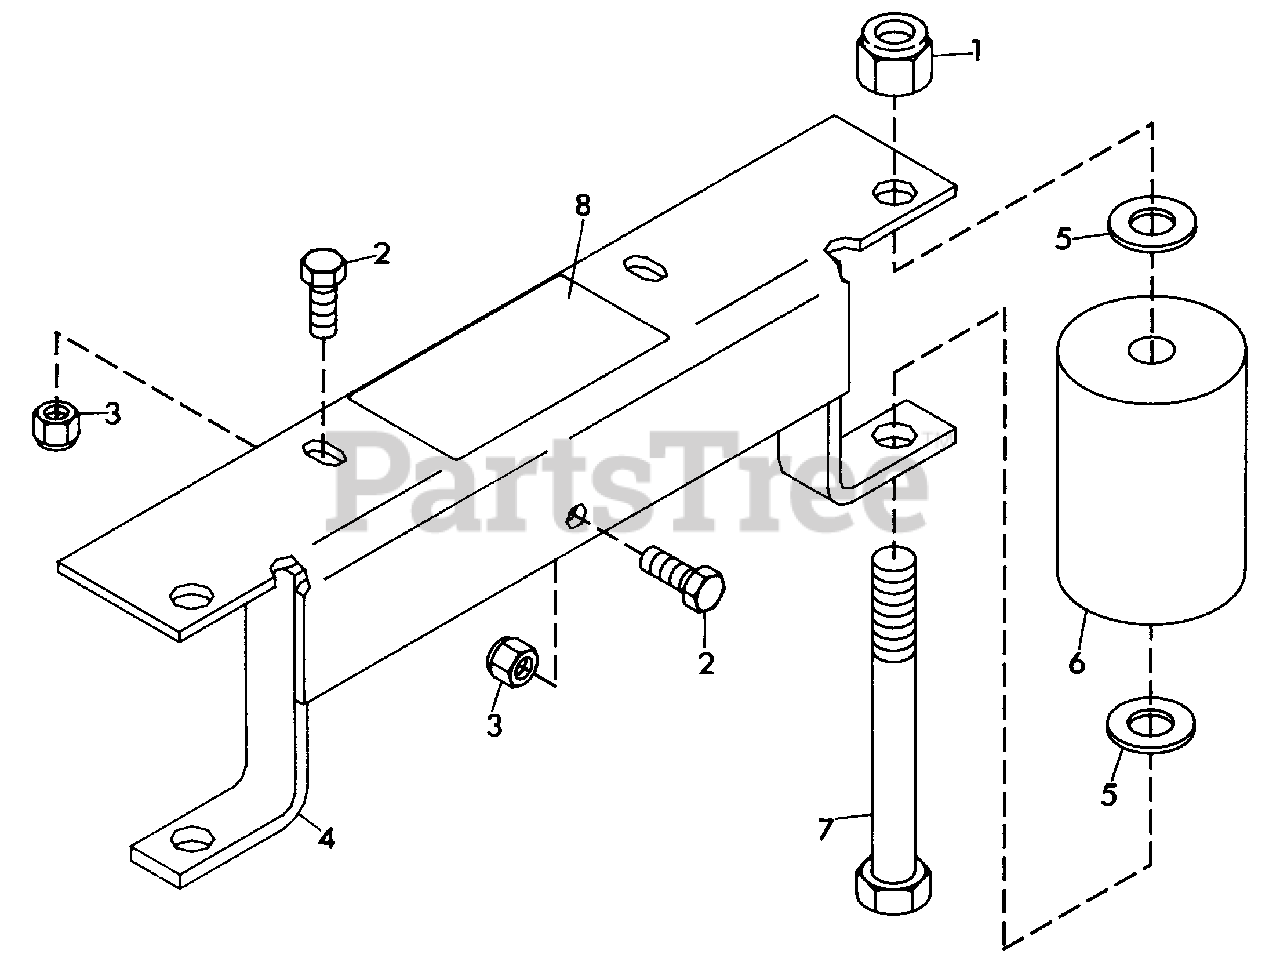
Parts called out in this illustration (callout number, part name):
1	NUT, LOCK 5/8-11
2	DECAL, DANGER FOOT
3	BOLT, HEX 5/8-11X5.50
4	BOLT, HEX 3/8-16X1.00
5	NUT, LOCK 3/8-16
6	WELDMENT, ROLLER BRACKET
7	NUT, LOCK 5/16-18
8	BOLT, HEX 5/16-18X1.00
9	WASHER, LOCK .656X1.250X.100
10	ROLLER, GAGE
